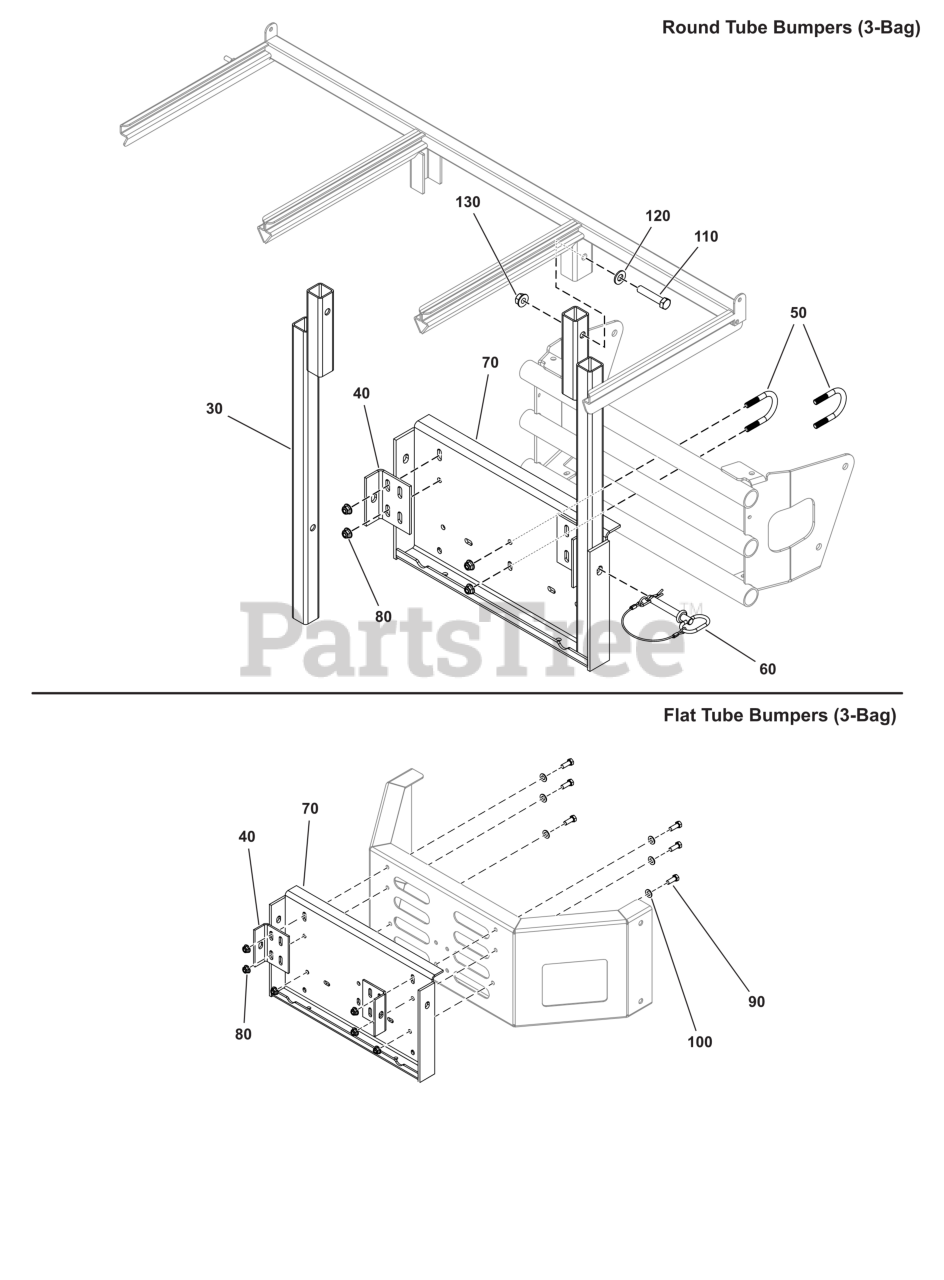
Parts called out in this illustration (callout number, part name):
40	BRACKET-MOUNTING
50	U-BOLT, 3/8 X 1-1/4
60	PIN, HITCH, .50 X 3.2
70	MOUNT, BAGGER
80	NUT, 3/8-16 HEX NYLOCK
90	BOLT, 3/8-16 X 1" GD5
110	BOLT, 1/2-13 X 2-1/2
120	WASHER, 1/2" SAE
